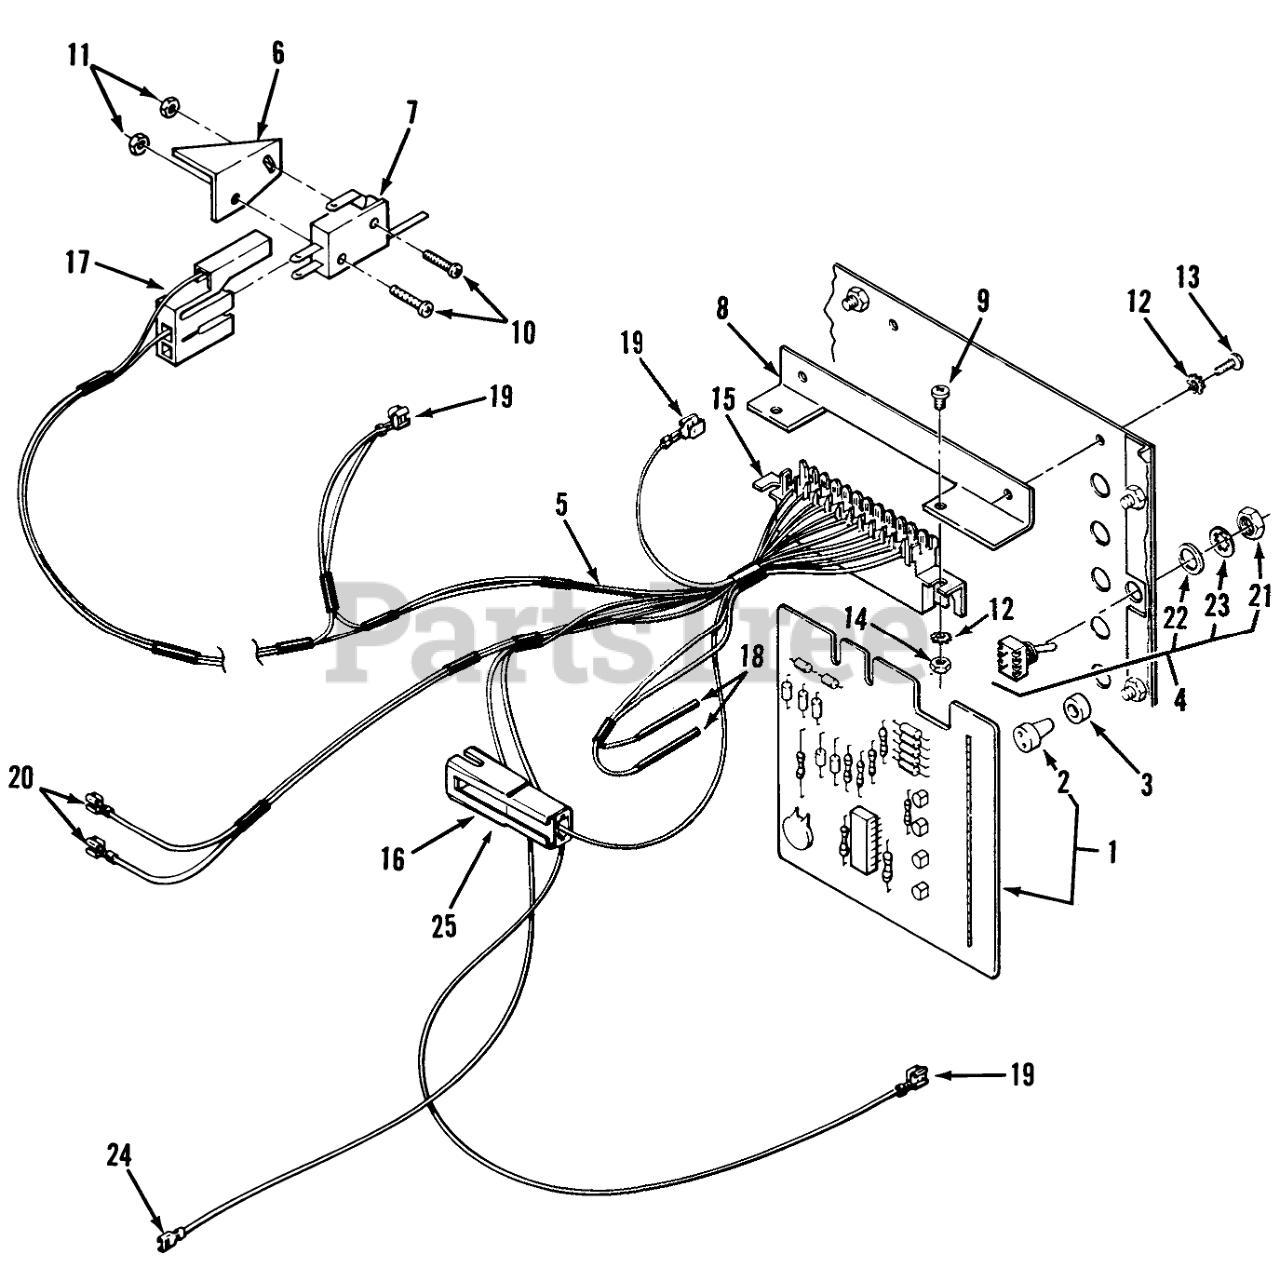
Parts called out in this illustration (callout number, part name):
1	P.C. Board (includes item 2)
2	LIGHT INDICATOR
3	ASSY LENS & BUSHING
4	SWITCH TOGGLE
5	Indicator Lights Wiring Harness
6	Brake Switch Bracket
7	SWITCH
8	Bracket
9	Screw #6-32 x 3/8
10	Screw
11	NUT HEX 4-40 ELAST
12	Washer-Lock
13	SCREW
14	Nut
15	Molex Connector (Part of 6)
16	Connector Part of 5
17	CONNECTOR BODY
18	062 X 031 TAB RECEPT
19	Piggy-Back Connector (Part of 6)
20	Piggy-Back Connector(Part of 6)
21	NUT F/W 116796
22	RING LOCKING
23	Washer
24	Female Terminal (part of item 5)
25	Connector Body
